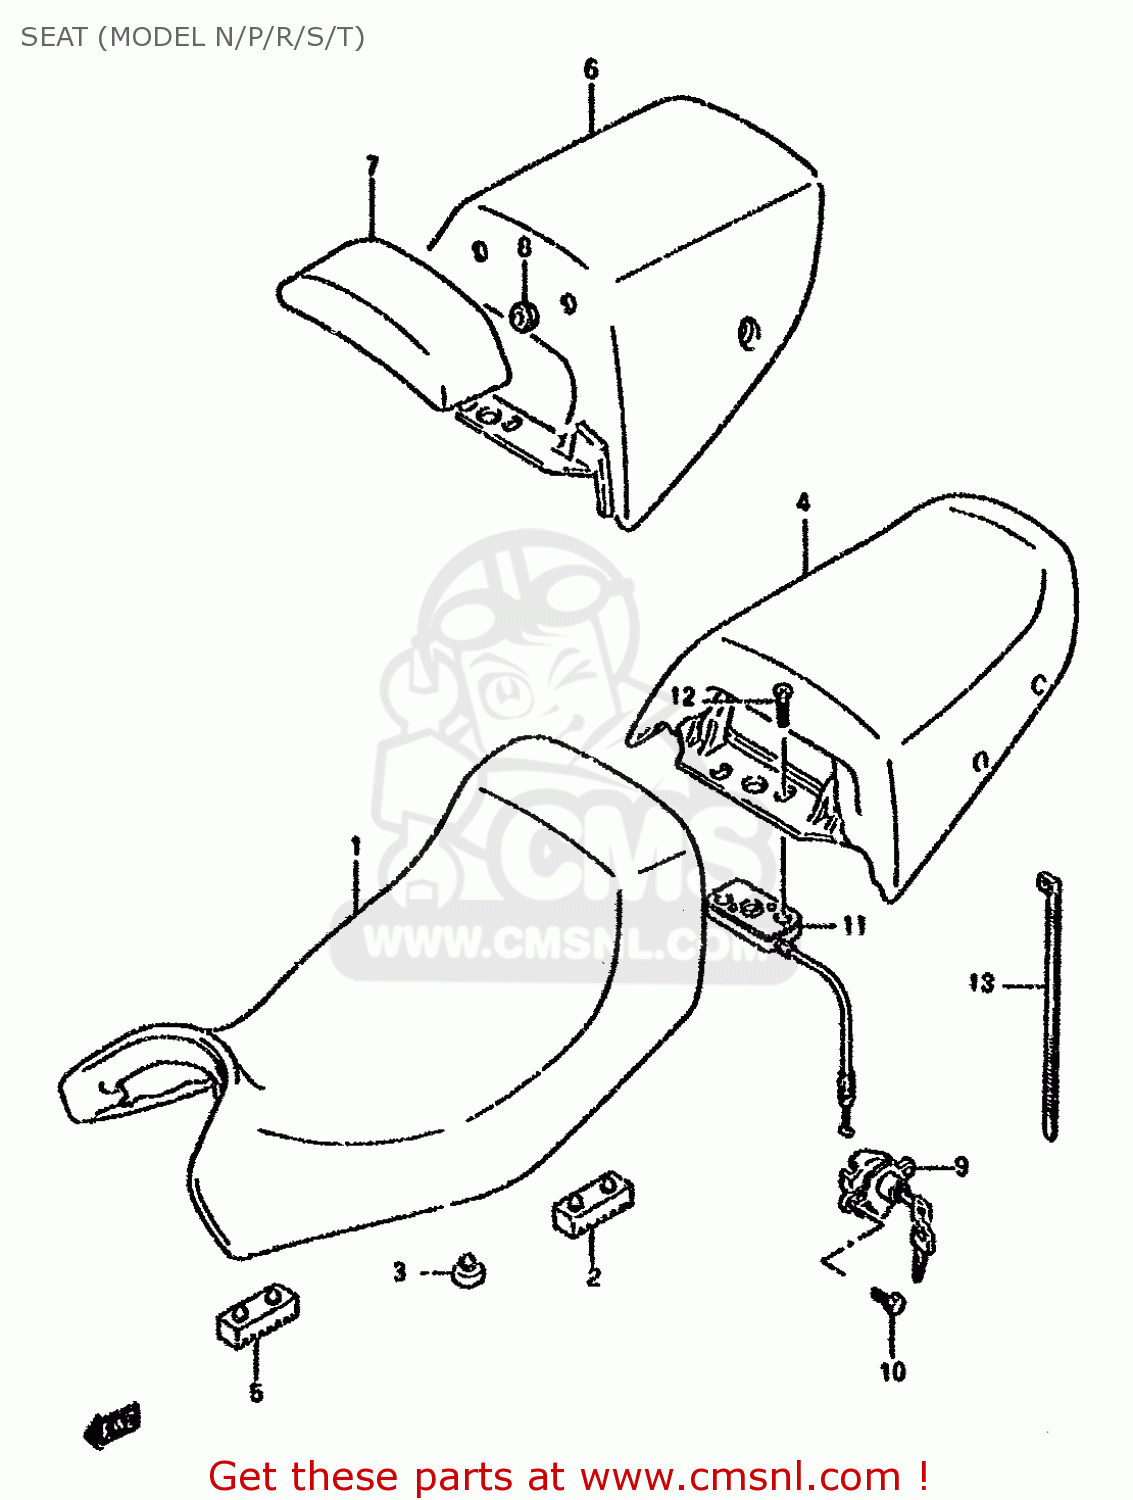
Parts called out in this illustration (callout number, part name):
1	SEAT SET
2	CUSHION,SEAT
3	CUSHION
4	SEAT SET,PILLION
5	CUSHION,SEAT(40X20X15)
6	TAIL COVER SET
7	PAD ASSEMBLY,TAIL COVER
8	CUSHION
9	LOCK SET,SEAT
10	BOLT
11	BRACKET,SEAT SUPPORT RR
12	SCREW
13	CLAMP L:165
